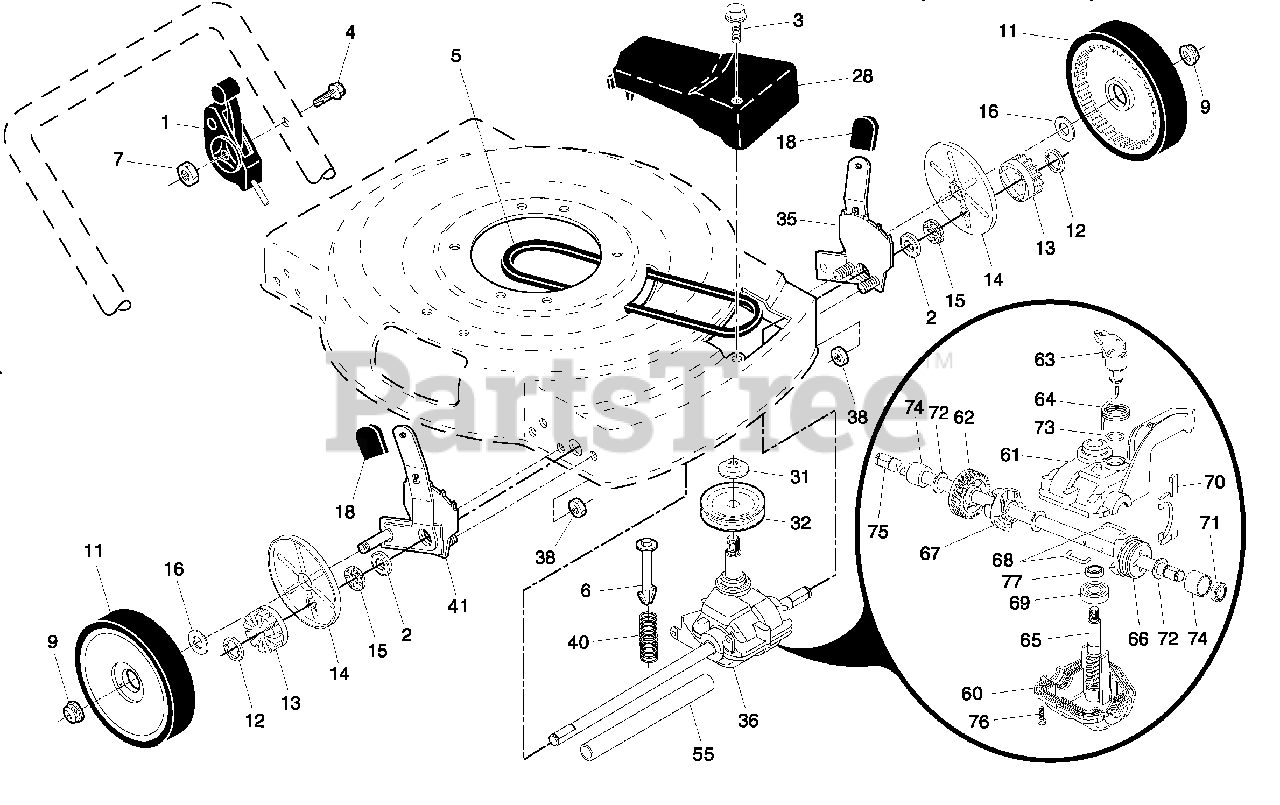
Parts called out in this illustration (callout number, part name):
1	Drive Control Assembly
2	Bearing, Wheel Adjuster
3	Screw, Tapping, Pan Head #10-24 x 2-3/4
4	Screw, Machine, Pan Head 1/4-20 x 2-3/16
6	Bolt, Hex Head 1/4-20 x 2
7	Nut, Hex, Flanged 1/4-20
9	Locknut
11	Wheel & Tire Assembly
12	E-Ring
13	Pinion
14	Dust Cover
16	Washer
18	Knob, Selector
28	Drive Cover
31	Locknut, Hex
32	Pulley, Drive
35	Kit, Wheel Adjuster, LH
36	Gear Case Assembly, Complete
38	Locknut, Hex
40	Spring
41	Kit, Wheel Adjuster, RH
55	Drive Shaft Cover
60	Case, Lower
61	Case, Upper
62	Gear, 27 Teeth
63	Lever, Clutch
64	Spring, Return
65	Shaft, Input
66	Dog, Movable
67	Dog, Fixed
68	Wire, Formed
69	Bearing, Ball
70	Fork, Shift
71	Seal, Output Shaft
72	Washer
73	Seal, Case
74	Bushing
75	Shaft, Output
76	Screw
77	Seal, Input Shaft
